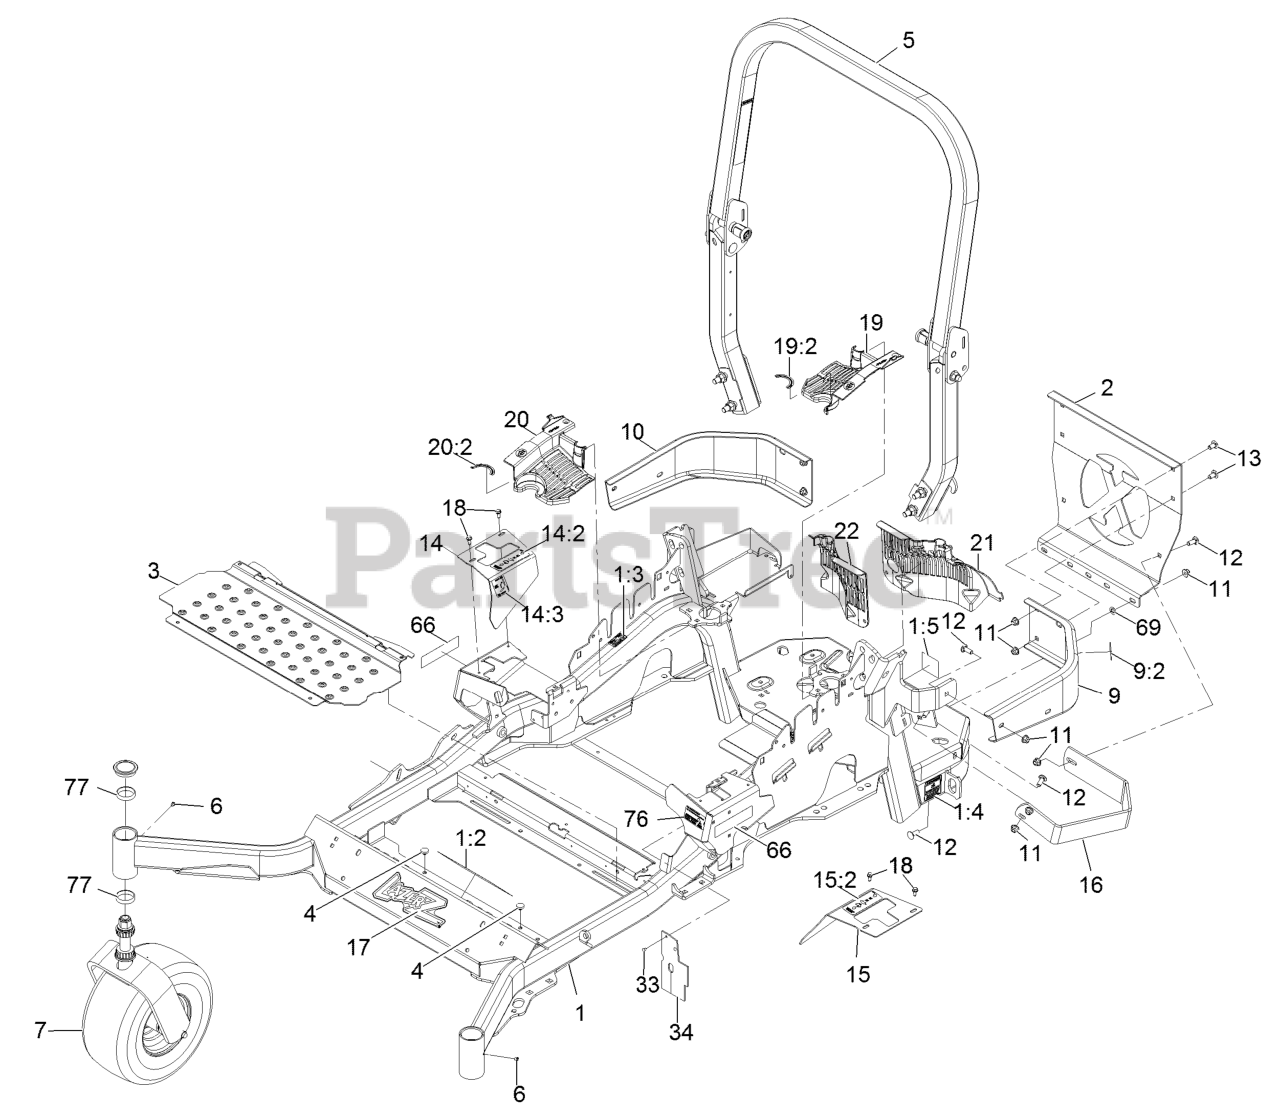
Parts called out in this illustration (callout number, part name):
1	MAINFRAME ASM
1:2	DECAL-SLOPE
1:3	DECAL-CAUTION
1:4	DECAL-BELT DRIVE
1:5	DECAL-SPARK ARRESTER
2	PLATE,REAR GUARD
5	ASM,ROPS SERVICE EXMARK
7	LH BUMPER ASM
9	DECAL-CAUTION
9:2	BUMPER-RH
10	NUT-HF, NI
11	SCREW-CARR
12	SCREW-CARR
13	RH MOTION CONTROL COVER ASM
14	DECAL-MOTION CONTROL
14:2	Decal-Motion Control
14:3	DECAL-PARK BRAKE
15	LH MOTION CONTROL COVER ASM
15:2	DECAL-MOTION CONTROL
16	GUARD-MUFFLER
17	DECAL,LAZER MODEL
18	SCREW-HWH
19	LH HYDRO GUARD ASM
19:2	DECAL-HYDRO OIL
20	RH HYDRO GUARD ASM
20:2	DECAL-HYDRO OIL
21	GUARD-HYDRO, REAR (LH)
22	GUARD-HYDRO, REAR (RH)
33	RIVET-POP
34	DEFLECTOR-AIR FLOW
66	DECAL-S-SERIES
69	NUT-PUSH
76	DECAL-FUEL FILL
77	CUP-BEARING
